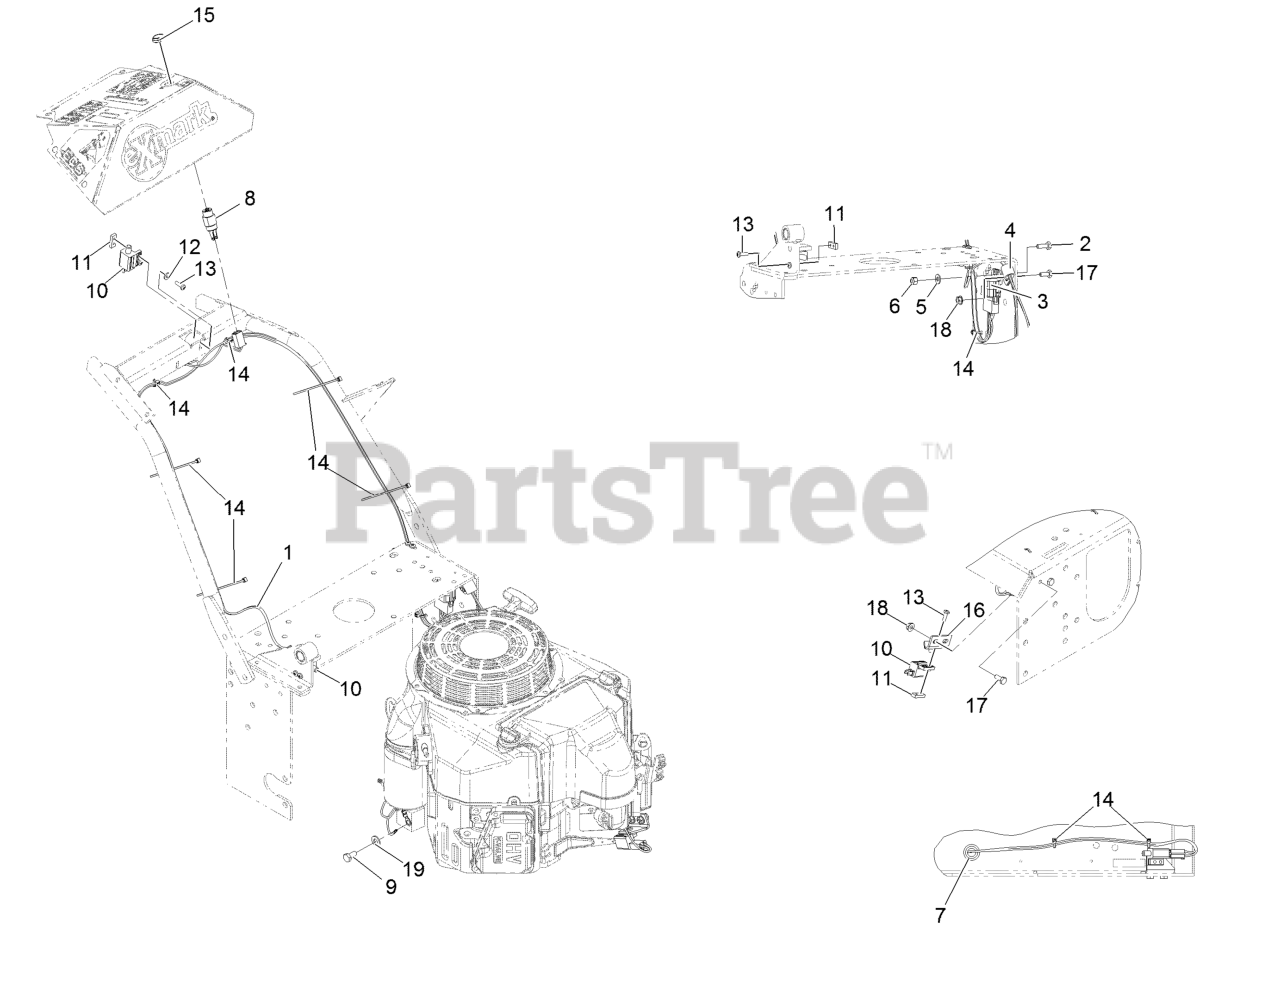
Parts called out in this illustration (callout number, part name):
1	Harness-Wiring
2	Screw-HH 1/4-20 X 3/4
3	Module-Interlock
4	Clip-Loom
5	Washer-1/4 SAE
6	Nut-Nyloc 1/4-20
7	Grommet
8	Switch & Key (Includes Nut & Washer)
9	Screw-HH M8-1.25 X 16Mm
10	Switch-N.O.
11	Plate-Tapped
12	Washer-#10 Std
13	Screw-PPH #10-24 X 5/8
14	Tie-Cable 5 1/2 (Small)
15	Nut-Ignition
16	Bracket-Switch, Blade
17	Screw-HH 1/4-20 X 5/8
18	Nut-Whizlock 1/4-20
